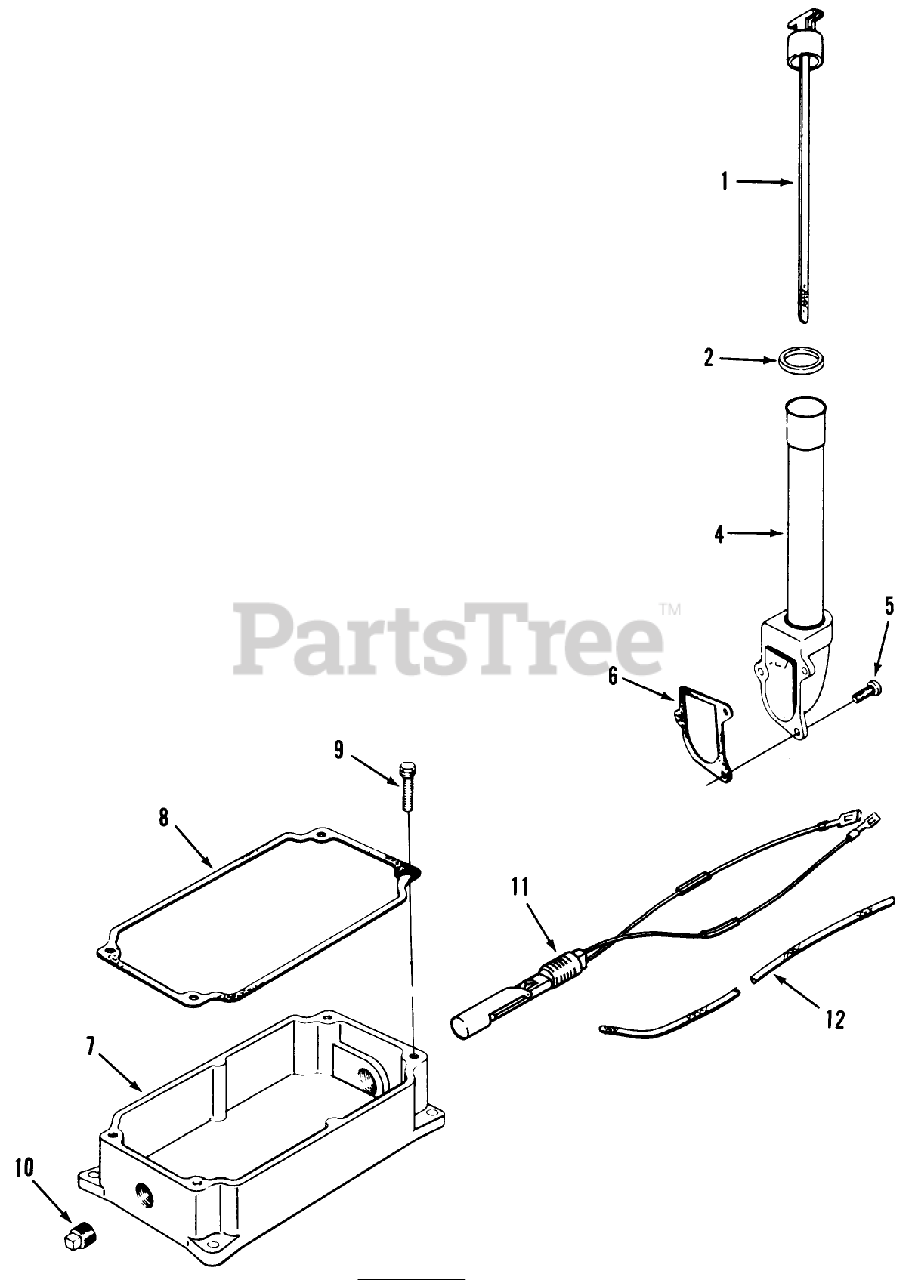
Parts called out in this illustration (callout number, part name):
1	KOHLER 47-038-27
2	KOHLER 41-153-01
4	KOHLER 47-029-06
5	KOHLER X-131-2
6	KOHLER 237064
7	KOHLER 47-199-05
8	KOHLER 235057
9	KOHLER X-159-3
10	KOHLER X-75-10
11	KOHLER 47-099-04
12	KOHLER 25-431-02
